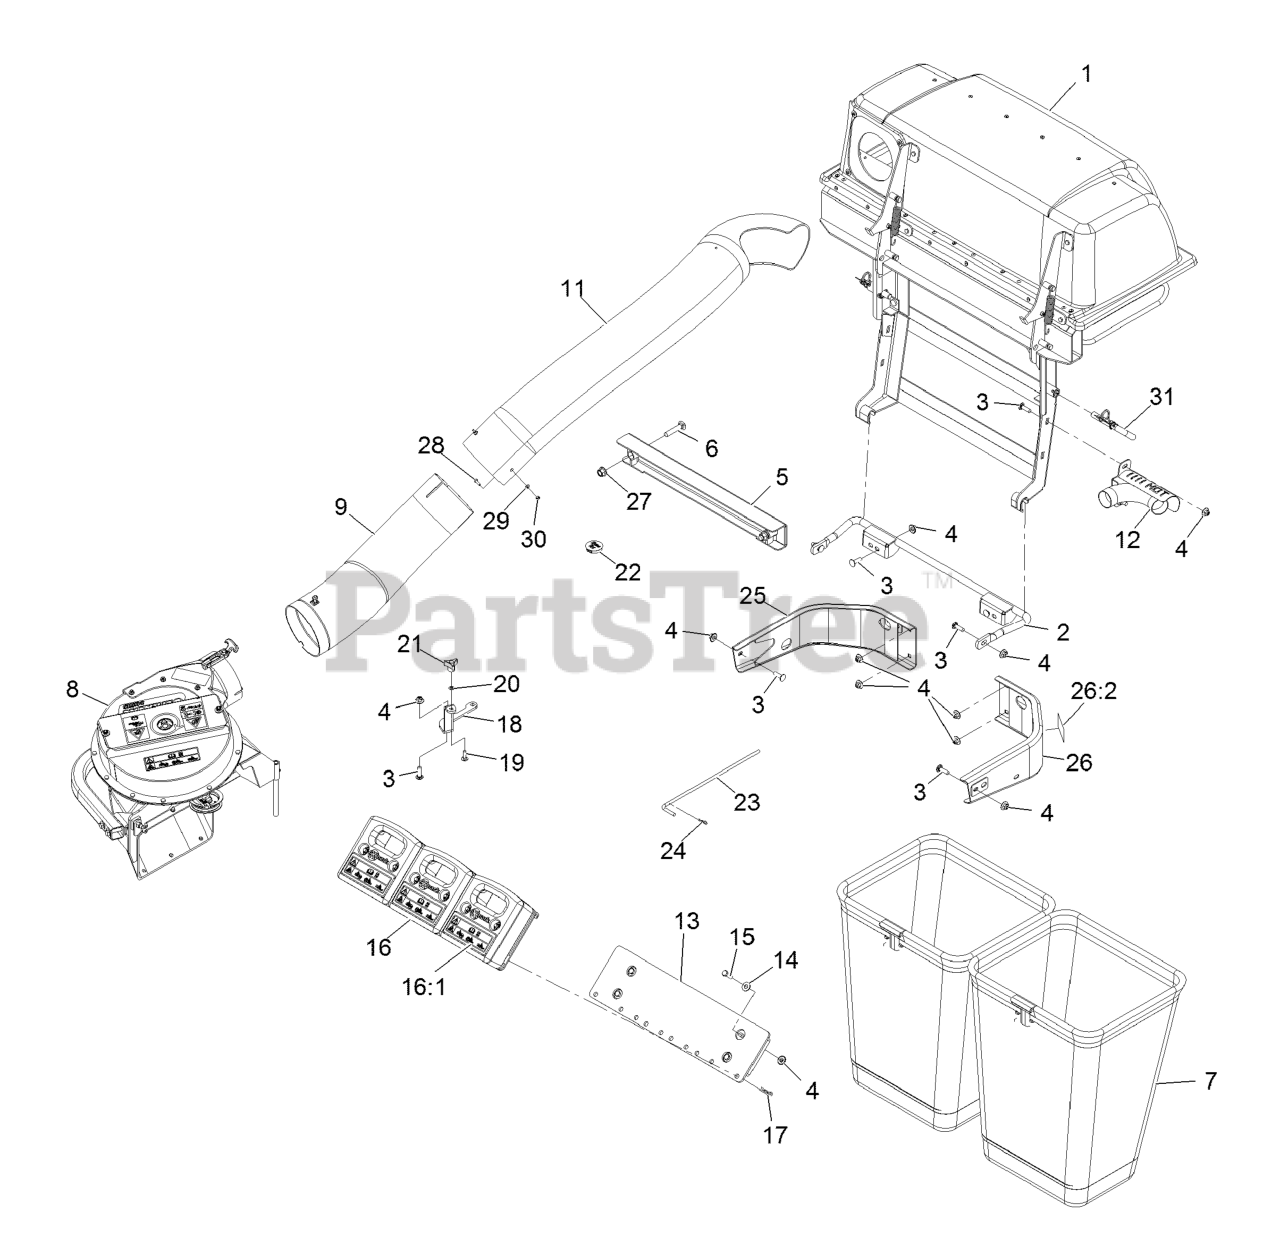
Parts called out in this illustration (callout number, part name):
2	MOUNT-BAGGER, LOWER
3	Bolt-Carriage 3/8-16 X 1 1/4
4	Nut-Nyloc 3/8-16 Flg
5	MOUNT-BAGGER, UPPER
6	SCREW-CARR
7	BAG AND FRAME ASM
8	ASM, BLOWER SMALL - SVC ONLY
9	LOWER TUBE ASM
11	TUBE-UPPER
12	EXHAUST DIVERTER ASM
13	WLD, MOUNT TOEBOARD WEIGHT
14	WASHER-FLAT
15	SCREW-HH
16	ASM,CAST WEIGHT
16:1	DECAL-WARNING WEIGHT
17	PIN-HAIR
18	BRACKET, SMALL UV BELT COVER
19	BOLT-CARR
20	RING-RETAINING, BOLT
21	KNOB-3 PRONG
22	PLUG, BLACK NYLON 1.75
23	PIN,CHUTE PIVOT
24	PIN-COTTER
25	BUMPER-RH
26	LH BUMPER ASM
26:2	DECAL-WARNING
27	Nut-Lock 1/2-13
28	SCREW-HWH
29	WASHER-FLAT
30	NUT-LOCK, NI
31	PIN-MOUNT, BAGGER
